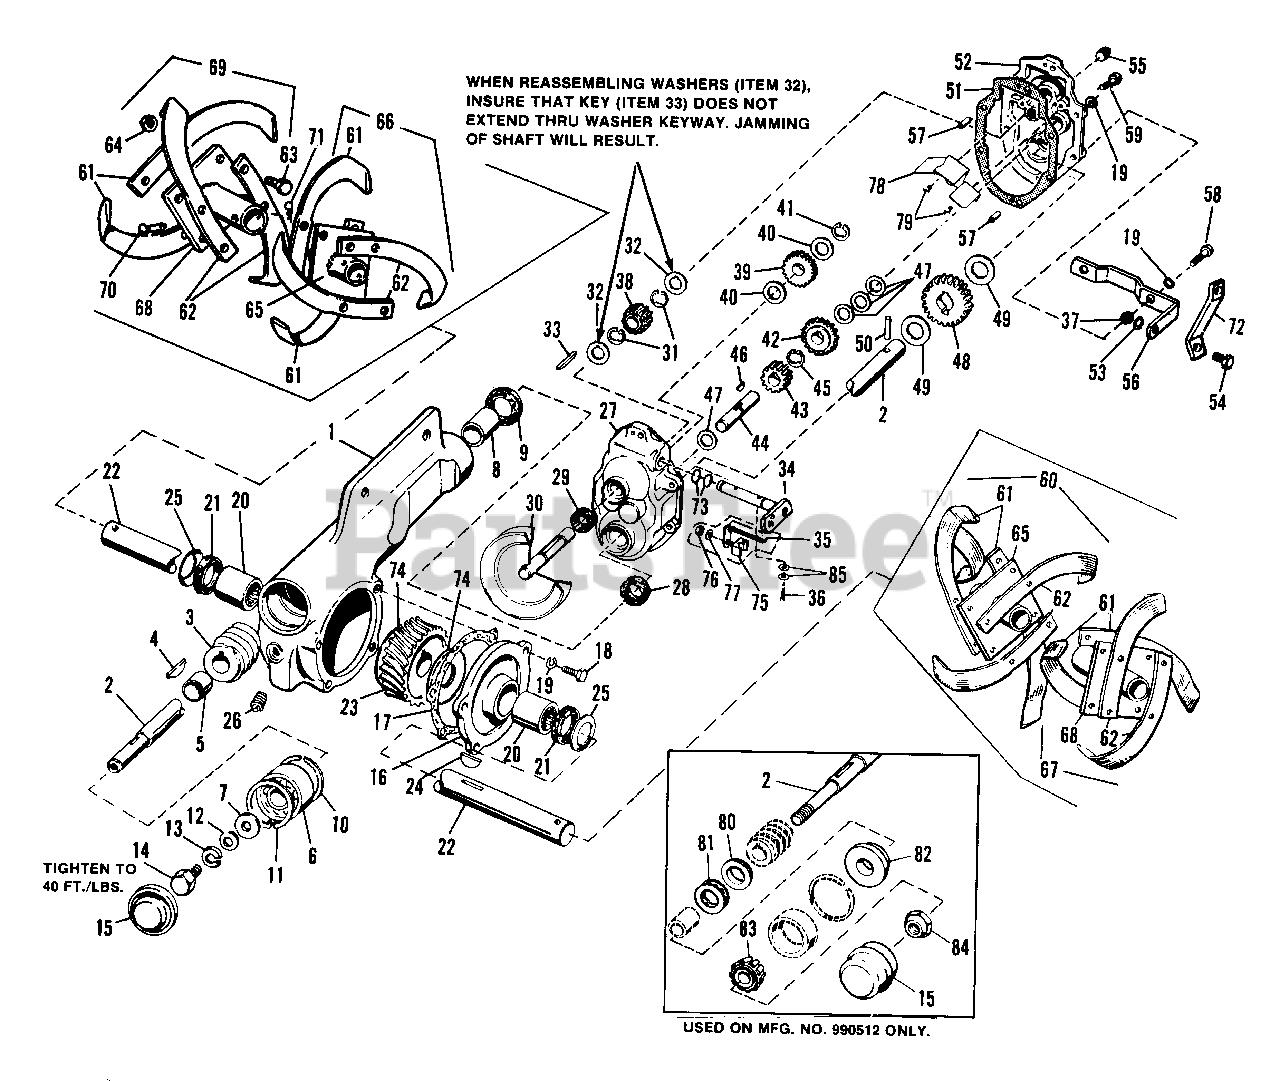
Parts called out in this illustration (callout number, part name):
1	HOUSING, Worm Drive
2	SHAFT, Worm
3	WORM
5	SPACER
6	BEARING, Ball
6	BEARING, Cup
7	WASHER
8	BUSHING
10	RING, Snap
11	RING, Retaining
12	WASHER, Plain, 5/16
13	LOCKWASHER, 3/8
14	CAPSCREW, Hex, 3/8-24
15	CUP
18	CAPSCREW, Hex, 1/4-20 x 5/8
19	LOCKWASHER, 1/4
20	BEARING, Needle
22	SHAFT, Worm
23	GEAR, Worm
24	KEY
25	WASHER, Cup
26	PLUG, Pipe, 3/8
27	CASE, Gear
30	PULLEY & SHAFT ASSY
31	RING, Retaining
32	WASHER, Special
34	LEVER ASSY, Shift
35	SHIFT KIT
35	BRACKET, Shift
36	SCREW, Socket Hd., #10-24 x 5/8
37	NUT, Hex, Full, 5/16-18
38	PINION, Shift
39	PINION, Reverse
40	WASHER, Special
41	RING, Retaining
44	SHAFT, Cluster
45	RING, Retaining
46	KEY
47	WASHER, Special
48	GEAR, Drive
49	WASHER, Special
50	PIN, Worm Shaft
52	COVER, Gear Case
53	LOCKWASHER, 5/16
54	CAPSCREW, Hex, 5/16-18 x 3/4
55	PLUG, Pipe, 1/4
56	ARM, Gear Case
56	ARM, Control
57	PIN, Roll
58	SCREW, Hex Hd., Thd. Form., 1/4-14 x 1-1/4
59	SCREW, Hex Hd., Thd. Form., 1/4-20 x 7/8
60	BLADE ASSY, L.H. Inner Tine
61	BLADE, L.H. Tine
62	BLADE, R.H. Tine
63	CAPSCREW, Hex, 7/16-20 x 1-1/4
64	NUT, Hex, Full, 7/16-20
65	PLATE ASSY, Inner Tine
66	BLADE ASSY, R.H. Inner Tine
67	EXTENSION, L.H. Tine
68	PLATE ASSY, Tine Extension
69	EXTENSION, R.H. Tine
70	PIN
71	CLIP, Spring
74	WASHER, Thrust
75	FORK, Shift
76	NUT, Hex, Full Lock, 1/4-20
77	WASHER, Plain
78	BAFFLE
79	SCREW, Hex Rd. Hd., Tapping, #10-32 x 5/16
80	WASHER, Thrust
81	BEARING, Thrust
82	SPACER, Thrust
83	BEARING, Roller
84	NUT, Special
85	WASHER, 3/16
